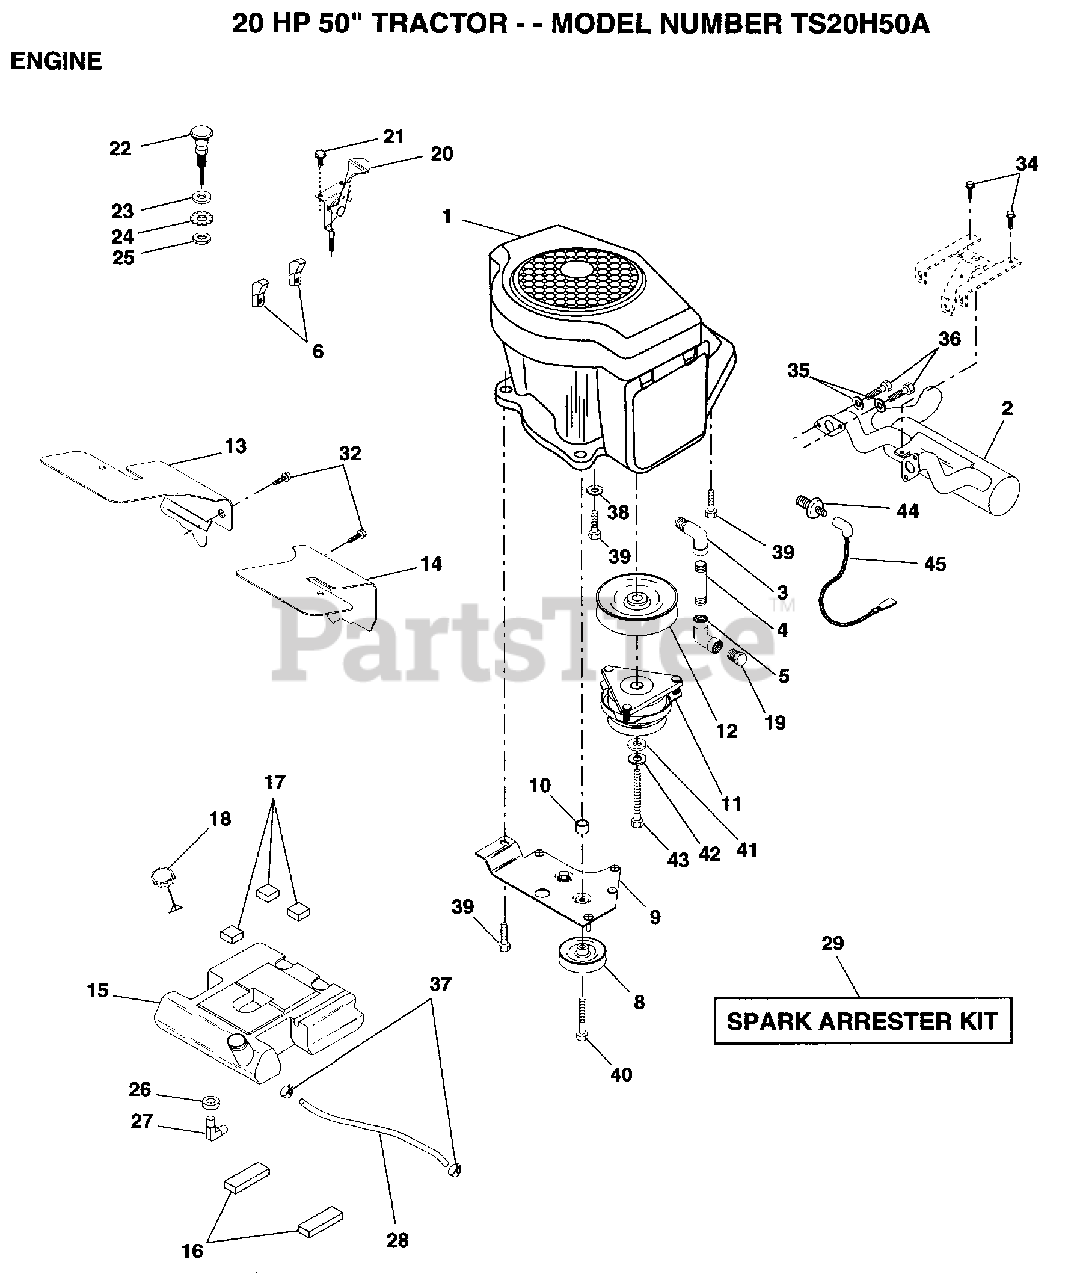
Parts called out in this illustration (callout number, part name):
1	ENGINE KOHLER MODEL
3	STREET ELBOW LT
4	PIPE NIPPLE
5	ELBOW
6	CLAMP.TUBE.DBL.EN
10	BUSHING.
12	PULLEY.ENGINE.VGT
13	BAFFLE.AIR.LH.K
16	PAD IDLER TI
17	PAD-SPACER LT
18	CAP ASM FUEL
19	PLUG T
20	CONTROL THTL 37
21	SCREW LT
22	"CONTROL.CHOKE.51"""
23	WASHER
24	LOCKWASHER
26	BUSHING OUTLET T
27	STEM.TANK.FUEL
29	SPARK ARREST KIT
32	SCREW LT
34	SCREW
35	LOCKWASHER
36	SCREW
37	HOSE CLAMP
38	LOCKWASHER
39	SCREW LT
40	SCREW.3/8-16X3.25
41	WASHER
42	LOCKWASHER
44	SWITCH OIL KOHLER
45	WIRE LEAD KOHLER
